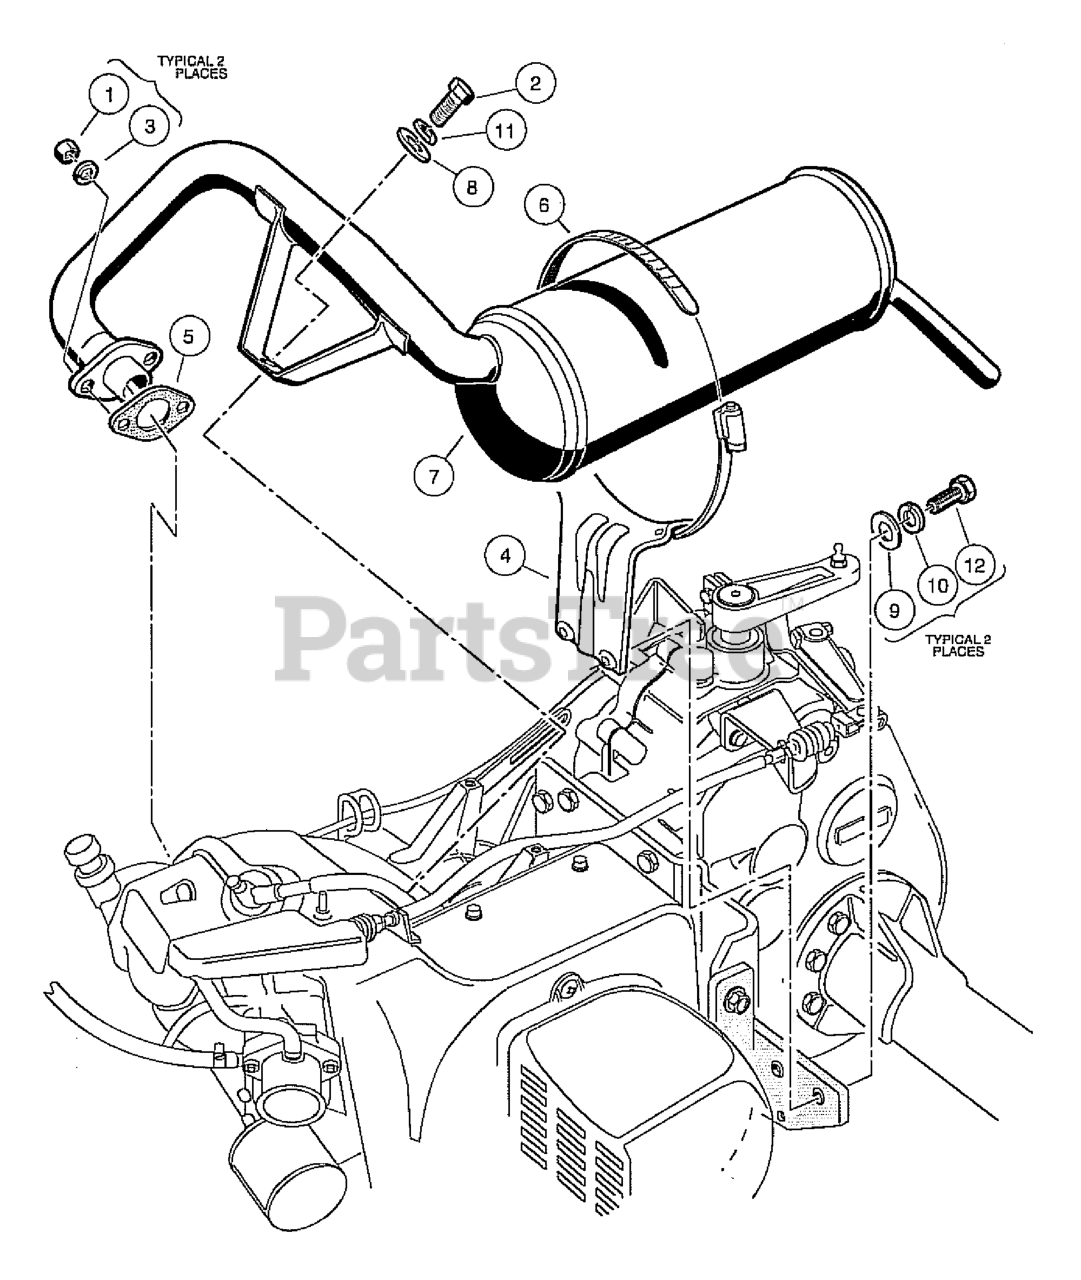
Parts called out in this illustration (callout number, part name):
1	NUT, M8-1.25 HEX
2	SCREW
4	BRACKET, MUFFLER MOUNTING
5	GASKET, FE350 EXHAUST
6	CLAMP, 5" MUFFLER HOSE
7	EXHAUST SYSTEM, FE350
8	WASHER, 5/16 TYPE A FLAT
9	WASHER 1/4 FLAT
10	LOCKWASHER, 1/4 HELICAL SPLIT
11	LOCKWASHER, 5/16 SPLIT
12	SCREW, 1/4-20 X .75 HEX
